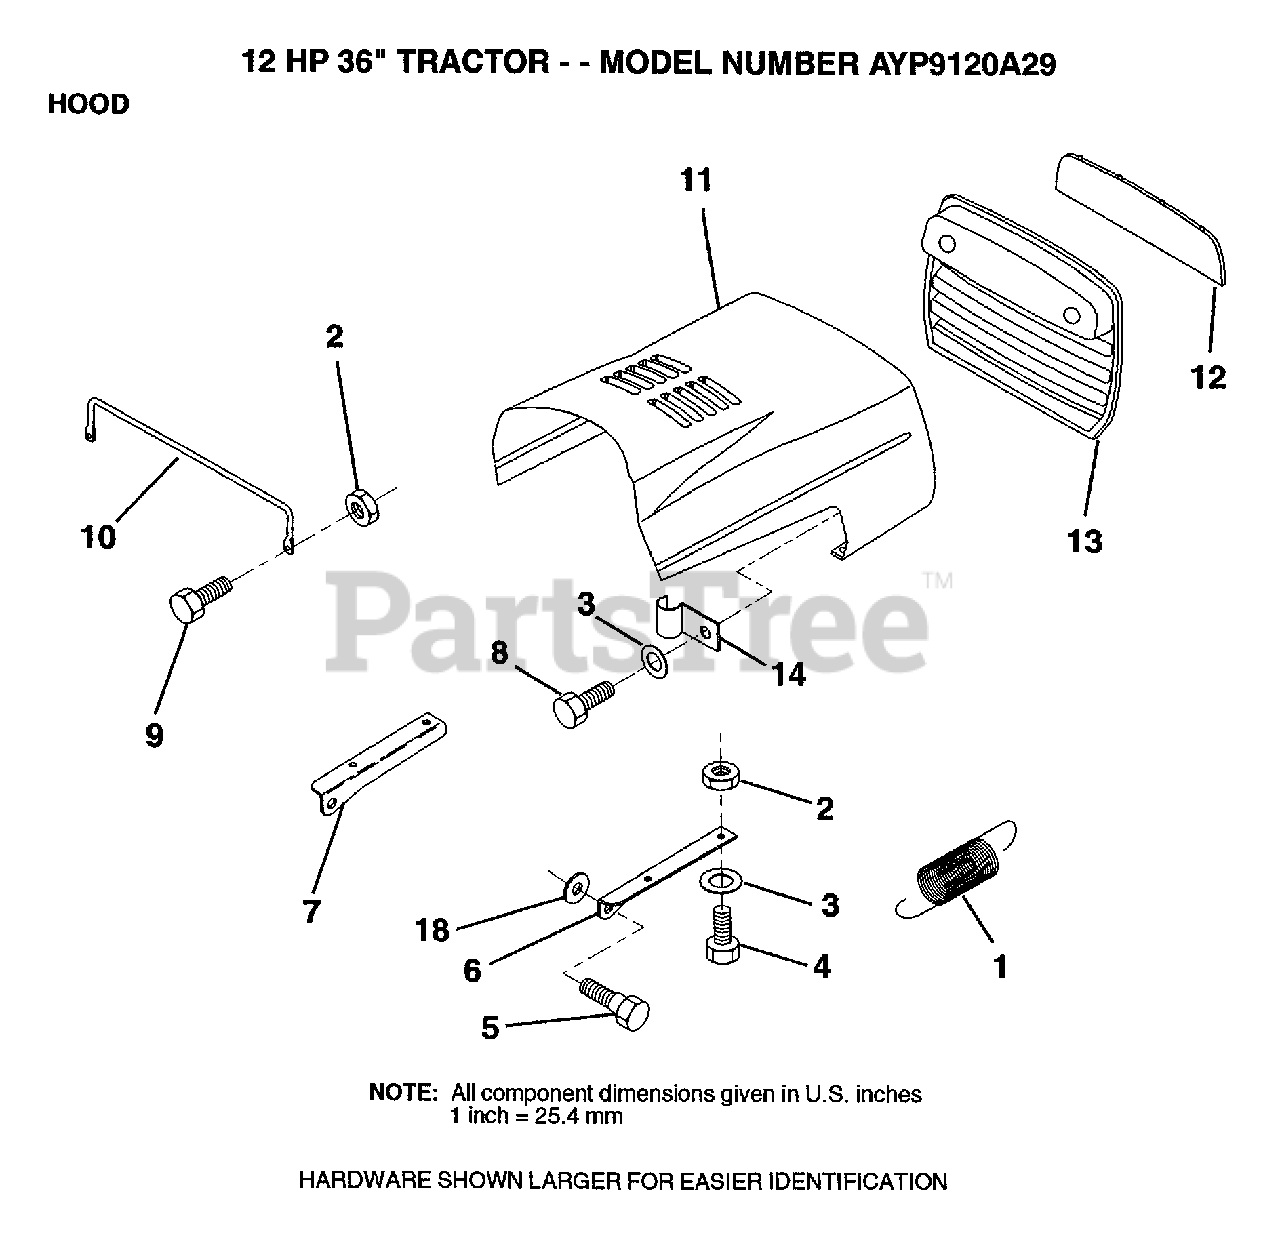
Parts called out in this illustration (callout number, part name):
1	EXT SPRING
2	NUT
3	WASHER
4	BOLT
6	BRKT HOOD RH
7	BRKT HOOD LH
10	"BRACE,HOOD"
11	HOOD
12	LENS
13	GRILL
14	CLIP T
18	WASHER
